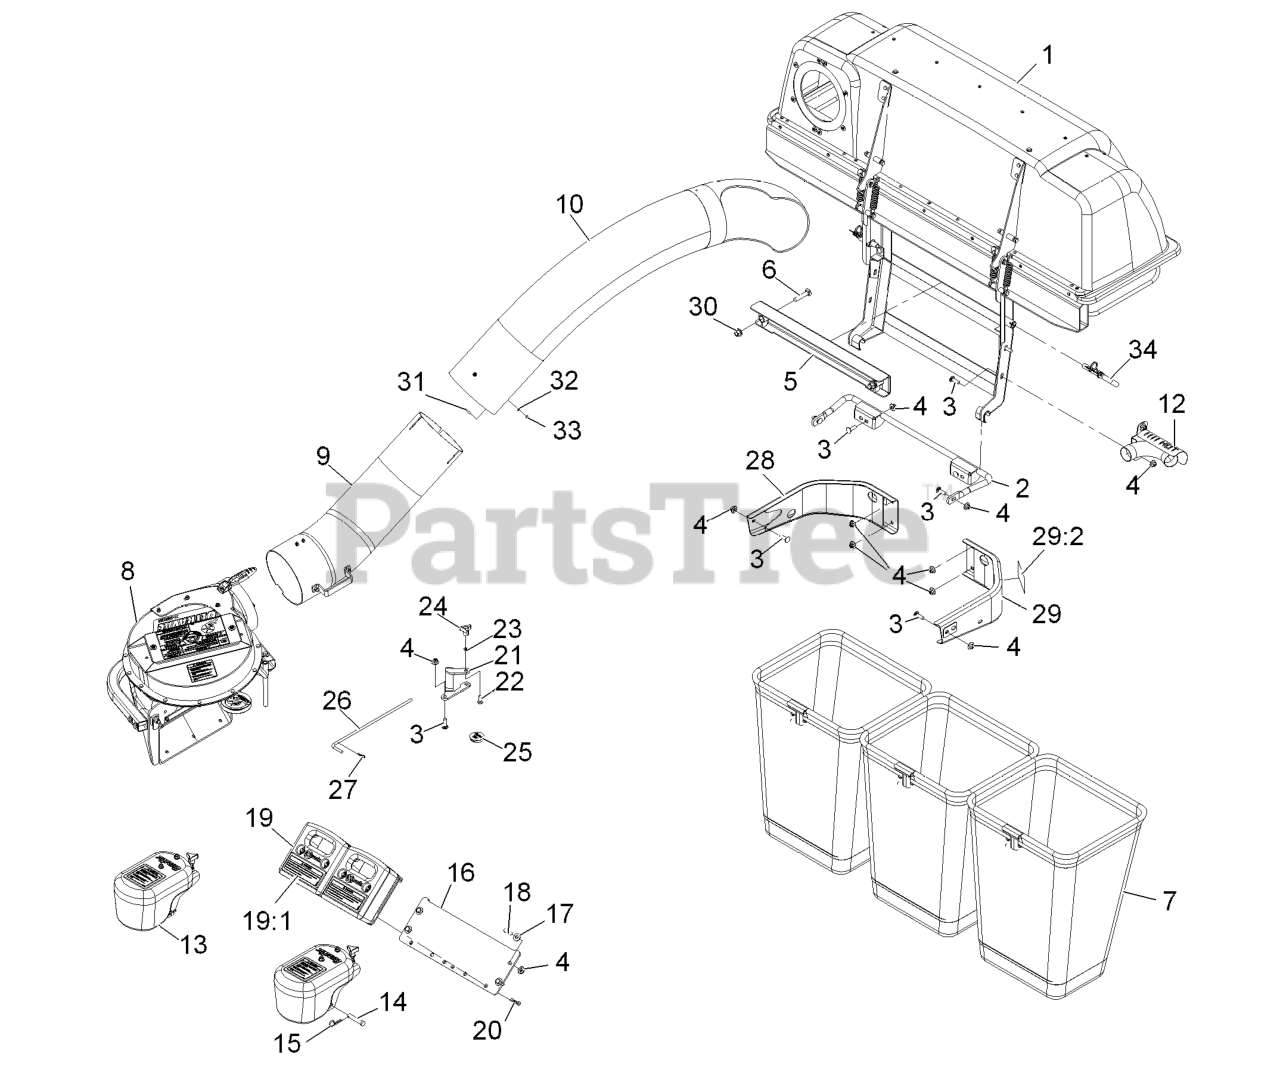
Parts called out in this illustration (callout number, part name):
1	Asm,Hood Uv 3 Bag
2	MOUNT-BAGGER, LOWER
3	Bolt-Carriage 3/8-16 X 1 1/4
4	Nut-Nyloc 3/8-16 Flg
5	MOUNT-BAGGER, UPPER
6	SCREW-CARR
7	BAG AND FRAME ASM
8	ASM, BLOWER LARGE - SVC O
9	LOWER TUBE ASM
10	TUBE-UPPER
12	EXHAUST DIVERTER ASM
13	ASM,CASTER WEIGHT
14	PIN-CLEVIS
15	PIN-COTTER
16	PLATE,WEIGHT ASM MOUNT
17	WASHER-FLAT
18	SCREW-HH
19	ASM,CAST WEIGHT
19:1	DECAL,WEIGHT
20	PIN-HAIR
21	BRACKET,BELT COVER
22	BOLT-CARR
23	RING-RETAINING, BOLT
24	KNOB-3 PRONG
25	PLUG, BLACK NYLON 1.75
26	PIN,CHUTE PIVOT
27	PIN-COTTER
28	BUMPER-RH
29	LH BUMPER ASM
29:2	DECAL-CAUTION
30	Nut-Lock 1/2-13
31	SCREW-HWH
32	WASHER-FLAT
33	NUT-LOCK, NI
34	PIN-MOUNT, BAGGER
